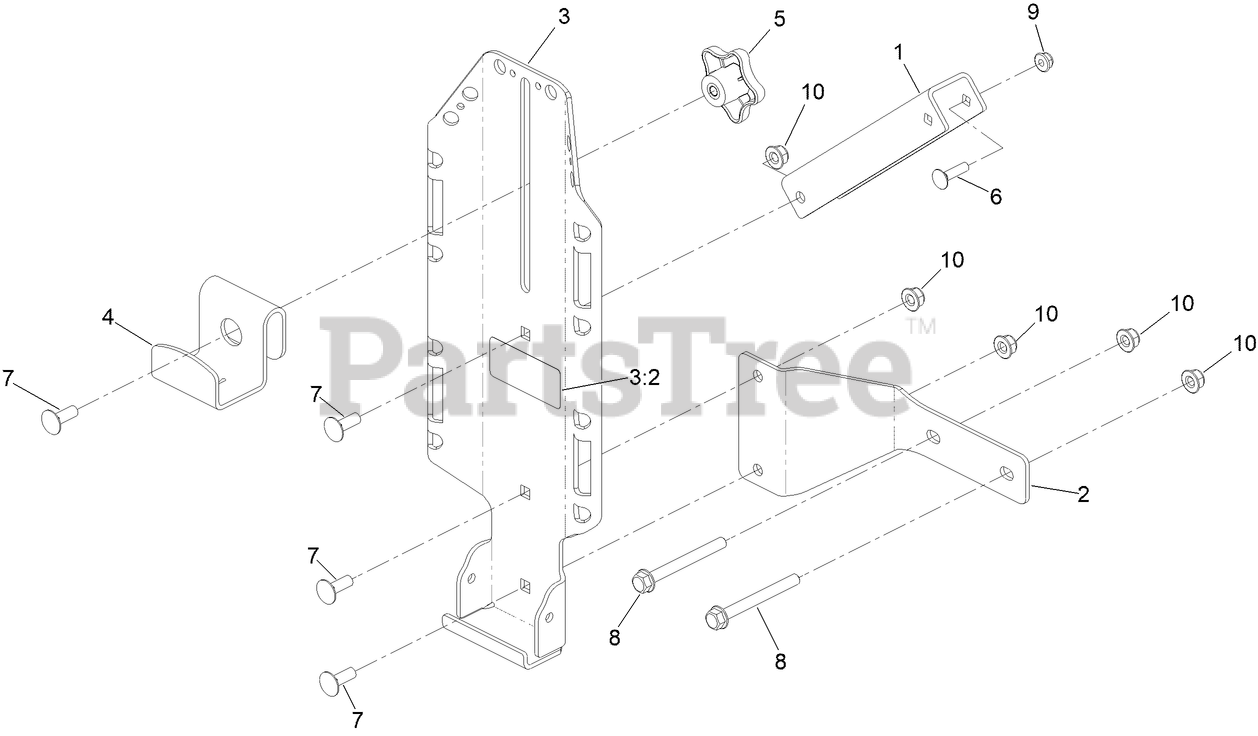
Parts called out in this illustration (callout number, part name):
1	PLATE-TOP BRACKET
2	PLATE-BOTTOM BRACKET
3	MOUNT BRACKET ASM
3:2	DECAL-WEIGHT, MAXIMUM
4	BRACKET-TOP
5	KNOB-HANDLE
6	BOLT-CARR
7	BOLT-CARR
8	SCREW-HHF
9	NUT-HF
10	NUT-HF, NI
